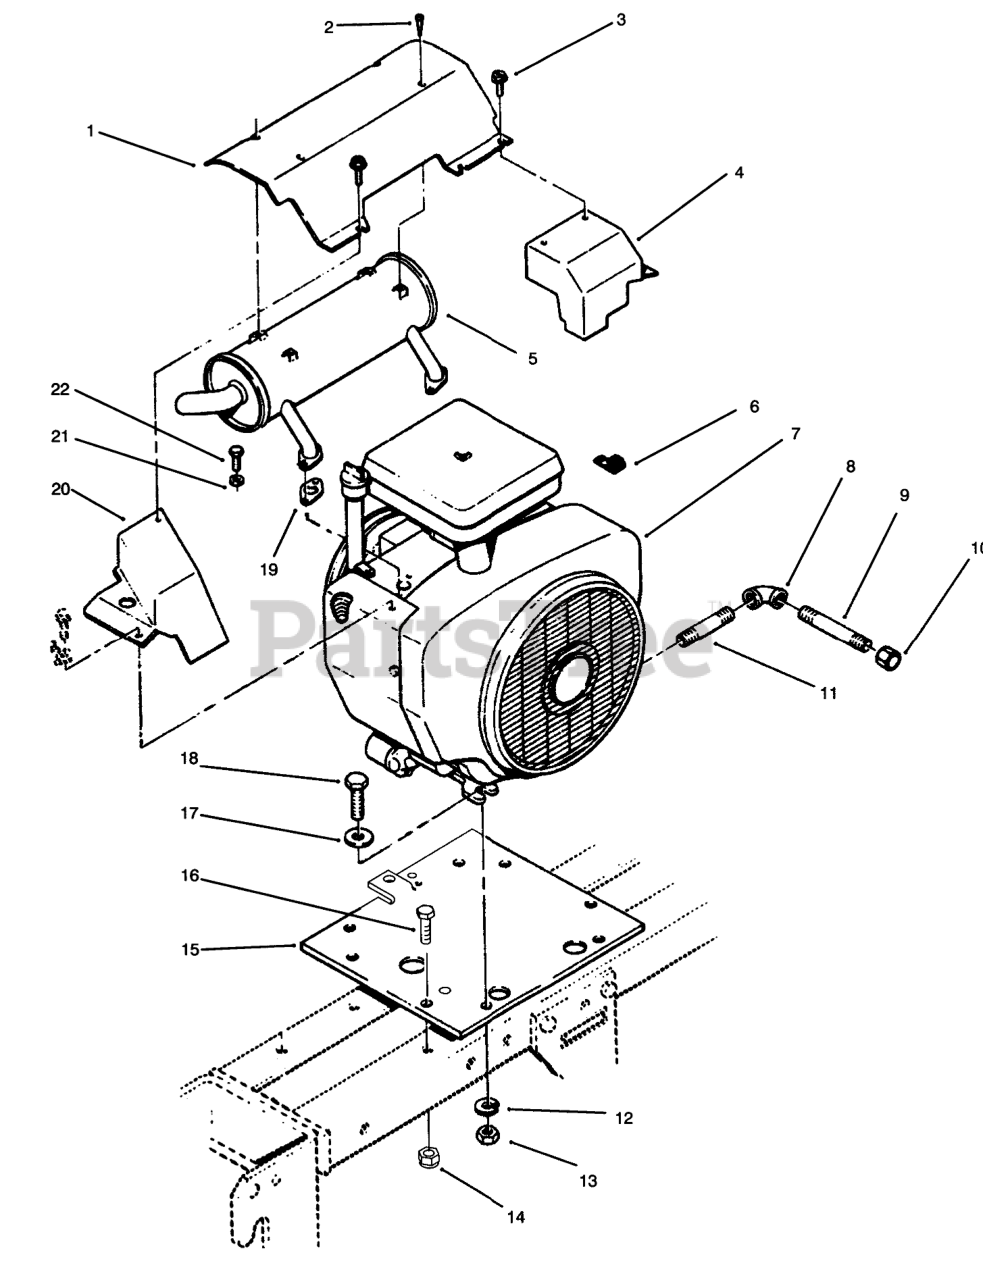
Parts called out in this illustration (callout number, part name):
1	Air Deflector
2	Screw
3	SCREW
4	RH Exhaust Cover
5	MUFFLER-EXHAUST
6	CLIP
7	Engine-20HP
8	ELBOW 3/8 90 DEG
9	PIPE-NIPPLE 3/8 X 4"
10	Cap
11	Pipe
12	WASHER-LOCK
13	NUT-HEX
14	NUT-LOCK, NI
15	PLATE-ENGINE B
16	SCREW-HH
17	WASHER-FLAT
18	SCREW-HH
19	Gasket-Exhaust
20	LH Exhaust Cover
21	WASHER-LOCK
22	SCREW-HH
